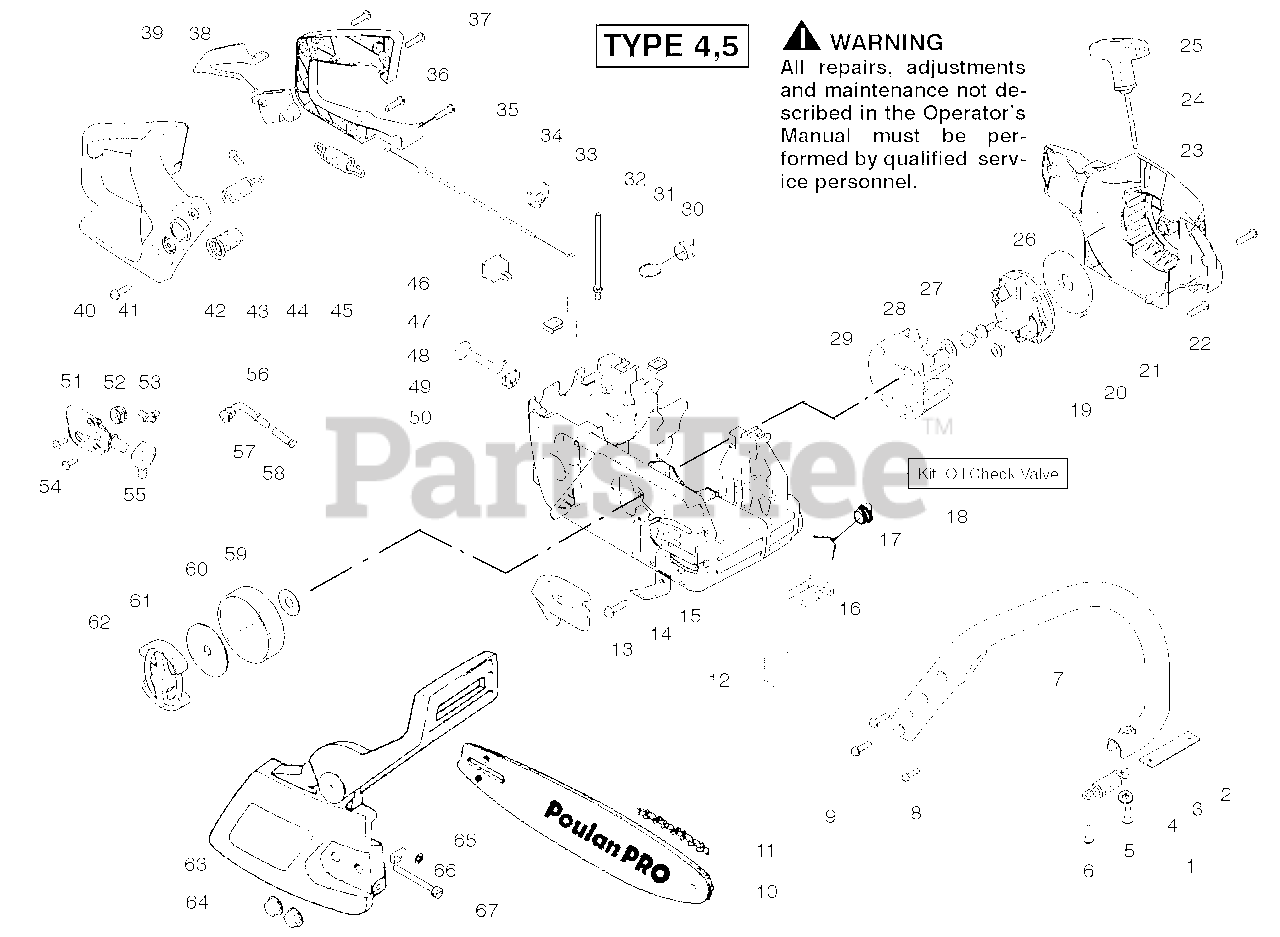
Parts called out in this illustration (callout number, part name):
1	Assy.- Isolator
2	Limiter Strap
3	Spring- Isolator
4	Washer
7	Front Handle
10	Bar-18" "Quick Adjust"
11	Chain-18"
13	Plate-Bar Mounting
15	Chain Catcher
16	Bolt-Bar
17	Oil Cap Ass'y.
18	Kit-Oil Check Valve
19	Nut- Flywheel
21	Starter Pulley
23	Fan Housing
24	Kit - Rope
25	Starter Handle
26	Recoil Spring
28	Washer- Flywheel
29	Assy- Flywheel
30	Fuel Cap Ass'y.
31	Fitting- fuel line
32	Kit-Fuel line (large)
33	Grommet-Cable
34	Cable-Throttle
35	Cover-Rear Handle
38	Throttle Lockout
39	Trigger-Throttle
40	Handle - Rear
42	Assy. Isolator - lower
43	Kit- Isolator (Upper)
45	Spring- Isolator
46	Kit-Switch
47	Nut- "U"-Type
48	Knob-Choke
49	Grommet-Knob
50	Assy-Chassis
51	Kit - Oil Pump
52	Gear-Worm Spring
53	Elbow-Oil Pickup
55	Seal Block
56	Assy-Oil Pick-up
57	Pick-up Oiler
58	Oil Filter
59	Washer-Thrust
60	Assy.-Clutch Drum w/bearing
61	Washer-Clutch
62	Assy. Clutch
63	Assy-Chain Brake
64	Nut-Bar Mounting
65	Pin-Bar Adjust
66	Retainer-Bar Adjust
67	Kit-Bar Adj.
